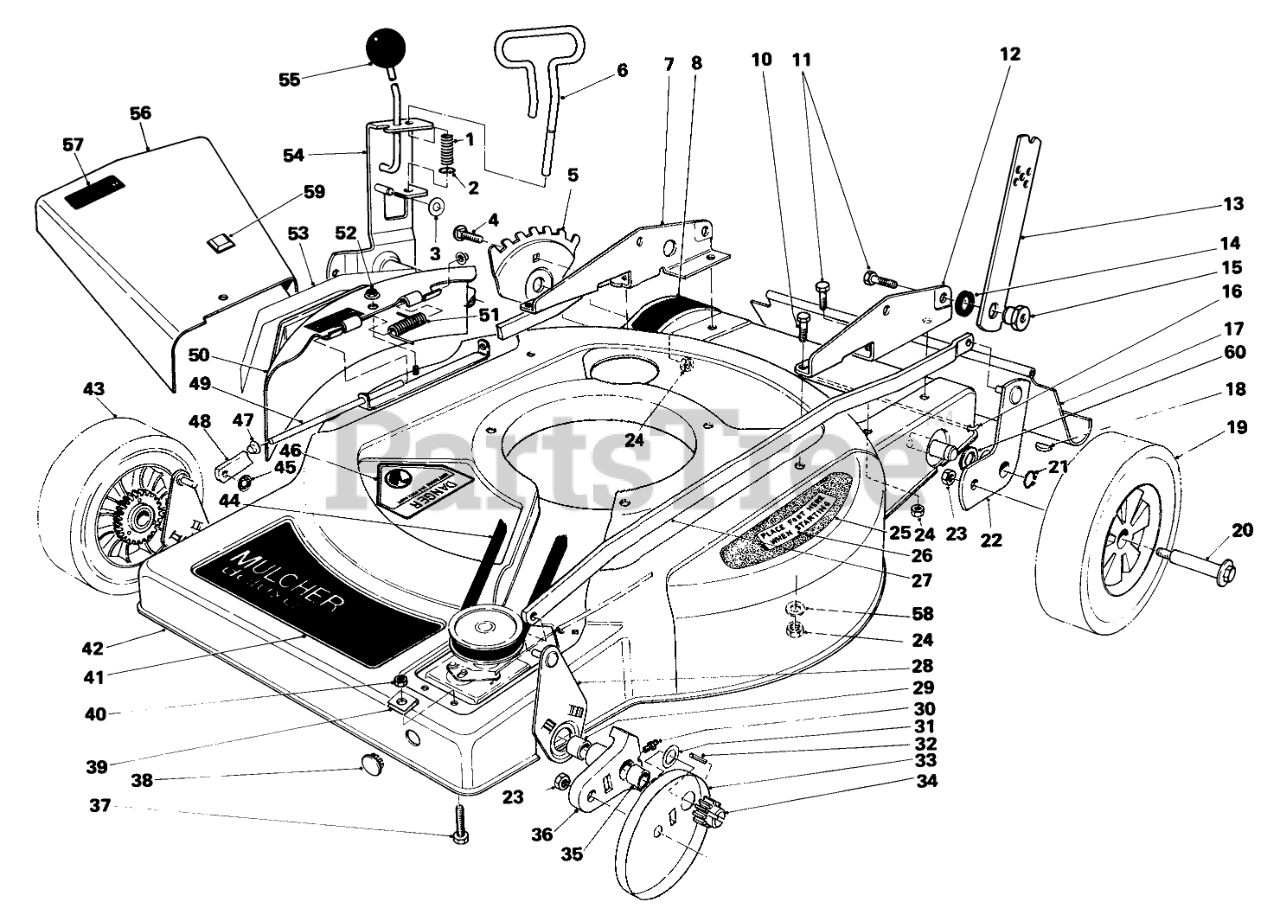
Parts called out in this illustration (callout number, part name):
1	SPRING-COMPRESSION
2	E-RING
3	WASHER-FLAT
4	Carriage Bolt
5	HOC ADJUSTMENT PLT
6	STOP ROD
7	Bracket Handle R.H.
8	Decal Height of Cut
10	SCREW-HH
11	SCREW-HH
12	Bracket-Handle R.H.
13	HANDLE LATCH
14	SPACER
15	HANDLE PIVOT NUT
16	SHIELD ROD
17	SHIELD - TRAILING
18	KEY-WOODRUFF
19	WHEEL & TIRE ASM
20	BOLT-WHEEL
21	RING-RETAINING
22	Pivot Arm
23	Nut
24	NUT-LOCK, CONE
25	PAD STEP
26	Decal Step Pad
27	Spanner Link L.H.
28	PIVOT ARM LINK WA
29	BUSHING
30	FITTING-GREASE
31	WASHER-THRUST
32	Pin
33	WHEEL COVER
34	Pinion
35	BUSHING
36	Pivot Arm Assembly (Incl. Ref. #29, 30 & 36)
37	SCREW
38	Hole Plug
39	SPEED NUT
40	NUT-JAM
41	Decal-Deck
42	Housing
43	Wheel & Gear Tire Assembly
44	V BELT
45	NUT-PUSH
46	DECAL-DANGER
47	PUSHNUT-CAP, WASHER
48	Spanner Link R.H.
49	DEFLECTOR PIVOT ROD
50	Mulcher Cover
51	Spring
53	Decal-Cover
54	Pivot Arm Bracket
56	Deflector-Grass
57	Decal-Danger
58	WASHER-FLAT
59	Bumper
60	WASHER-FLAT
